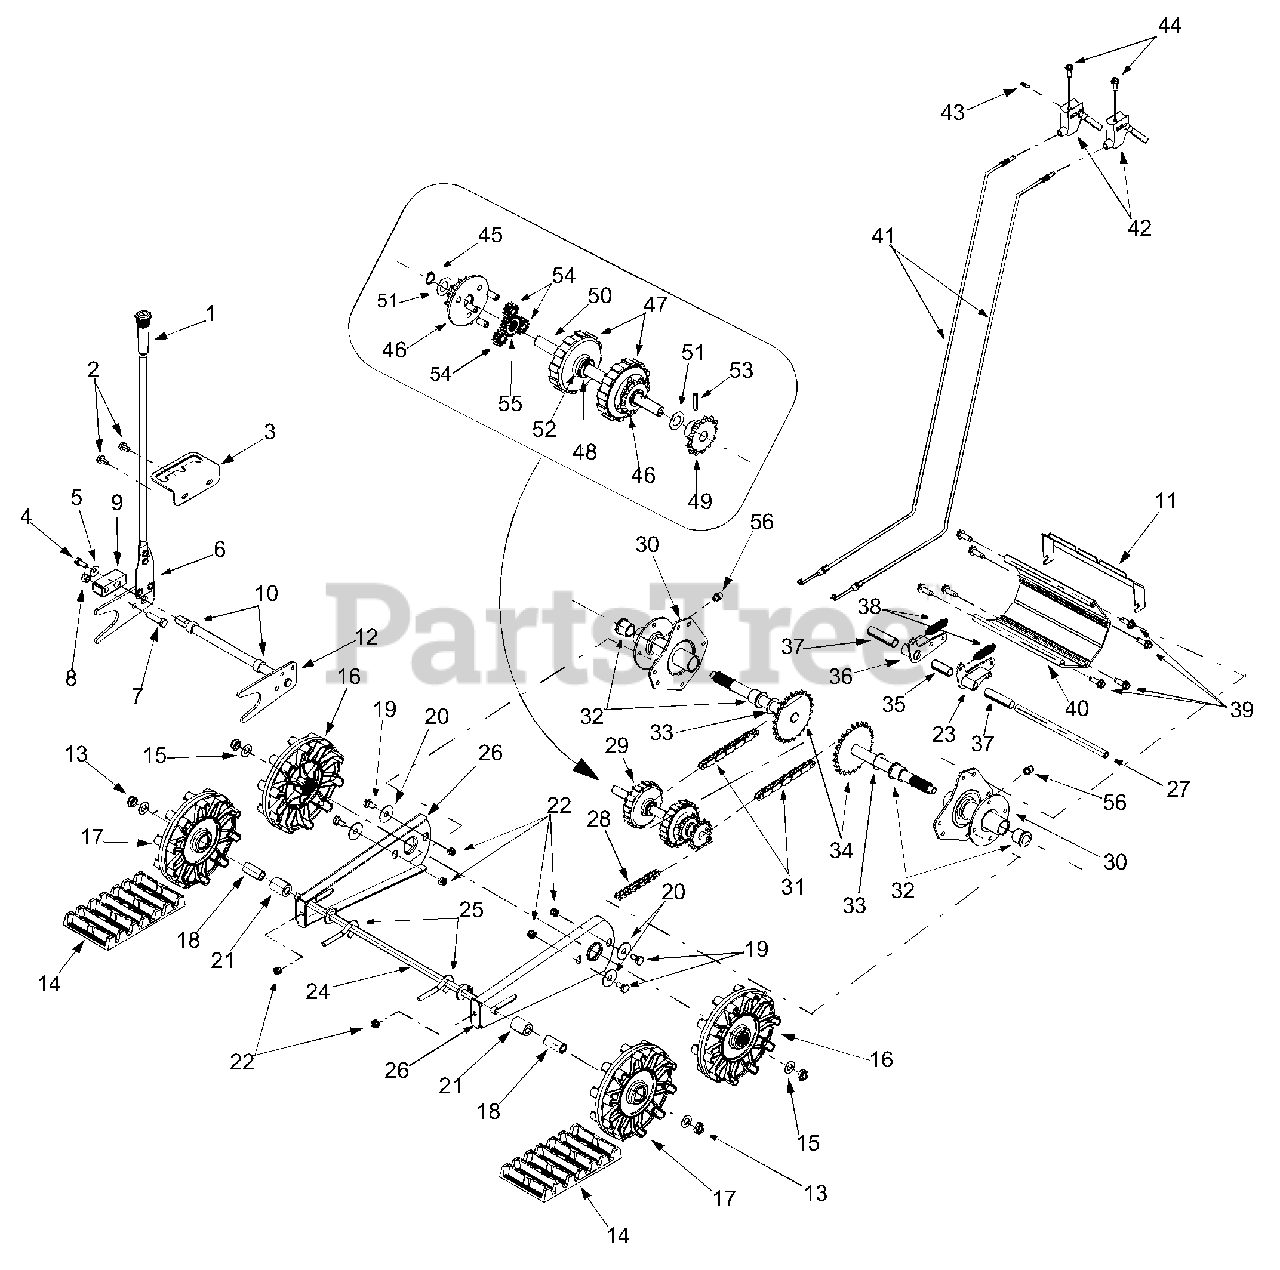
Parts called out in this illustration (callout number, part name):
2	Tap Screw, 5/16-18 x .625
4	Hex Cap Screw, 5/16-24 x .75
5	Bell Washer, .34 ID x .872 OD
7	Hex Cap Screw, 3/8-24 x 1.5
8	Hex Nut, 3/8-24
9	Lift Shaft Drive
10	Spacer, .628 ID x .875 OD x .5
13	Jam Nut, 1/2-20
14	Snow Track
15	Flat Washer, .5 x 1 x .06
16	Track Drive Wheel
17	Track Idler Wheel
18	Spacer, .51 ID x .75 OD x 1.67
19	Screw, .435 x .178-5/16 x .56
20	Flat Washer, .442 x 1.38 x .06
21	Spacer, .51 ID x 1 OD x 1.34
22	Hex Nut, 5/16-18
23	LH Dogg Assembly
25	Eye Bolt, 5/16-18 x 3
27	Actuator Shaft
28	Chain
29	Track/Steering Shaft Assy
31	Chain
32	Flange Bearing
33	Flat Washer, .793 x 1.24 x .06
34	Axle Assembly
35	Spacer, .514 x .630 x 1.59
36	RH Dogg Assembly
37	Spacer, .514 x .630 x 2.44
38	Extension Spring
39	Tap Screw, 5/16-18 x 1
40	Track Housing
41	Steering Cable
42	Steering Trigger
43	Flange Nut
44	Screw, #10-24 x 1.375
45	Retaining Ring
46	Carrier Assembly
47	Ring Gear
48	Retaining Ring
49	13-Tooth Sprocket
50	Track Steering Drive Shaft
51	Flat Washer, .58 x 1.06 x .02
52	Flat Washer, 5/8 x 1 x .03
53	Spiral Pin, 3/16 x 1
54	12-Tooth Gear
55	18-Tooth Gear
